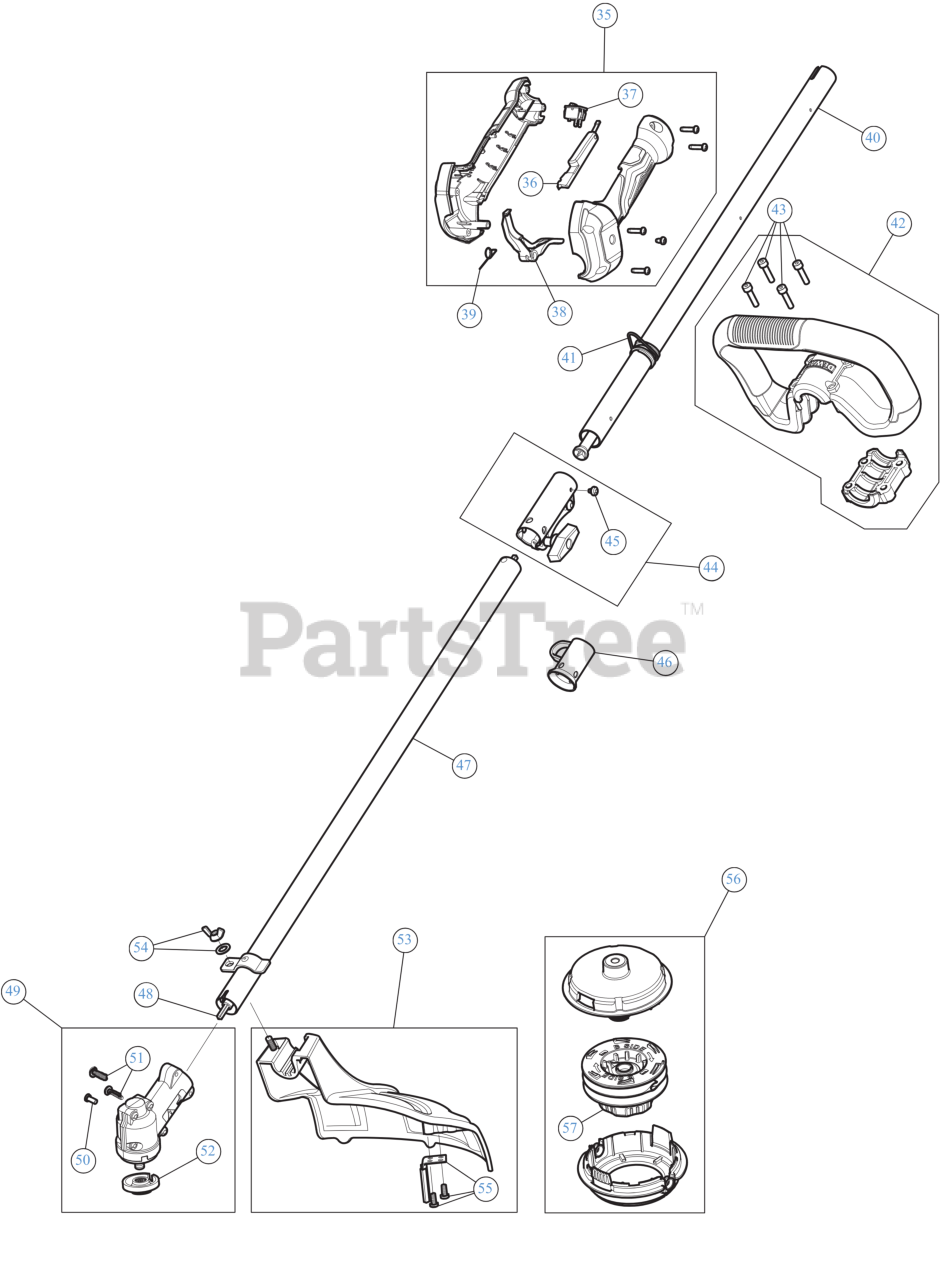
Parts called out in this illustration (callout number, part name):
35	THROTTLE GRIP
36	THROTTLE LOCK LEVER
37	SW, MOMENTARY ON/O
38	THROTTLE TRIGGER
39	TRIGGER SPRING
40	UPPER DRIVE SHAFT
41	CLAMP-SHOULDER STR
42	HANDLE
43	HANDLE BOLT
44	CLICK LINK
45	SCREW, 10-32X.250 TA
46	HANGER
47	LOWER SHAFT HOUSING
48	LOWER DRIVE SHAFT
49	GEARBOX LCBC
50	SCREW, 8-32 x .312 P
51	SCREW #
52	CUTTING HEAD SPACER
53	GUARD
54	BLADE GUARD MOUNTING HARDWARE
55	BLADE ASSEMBLY W/HDW
56	CUTTING HEAD (LH)
57	BUMP KNOB
